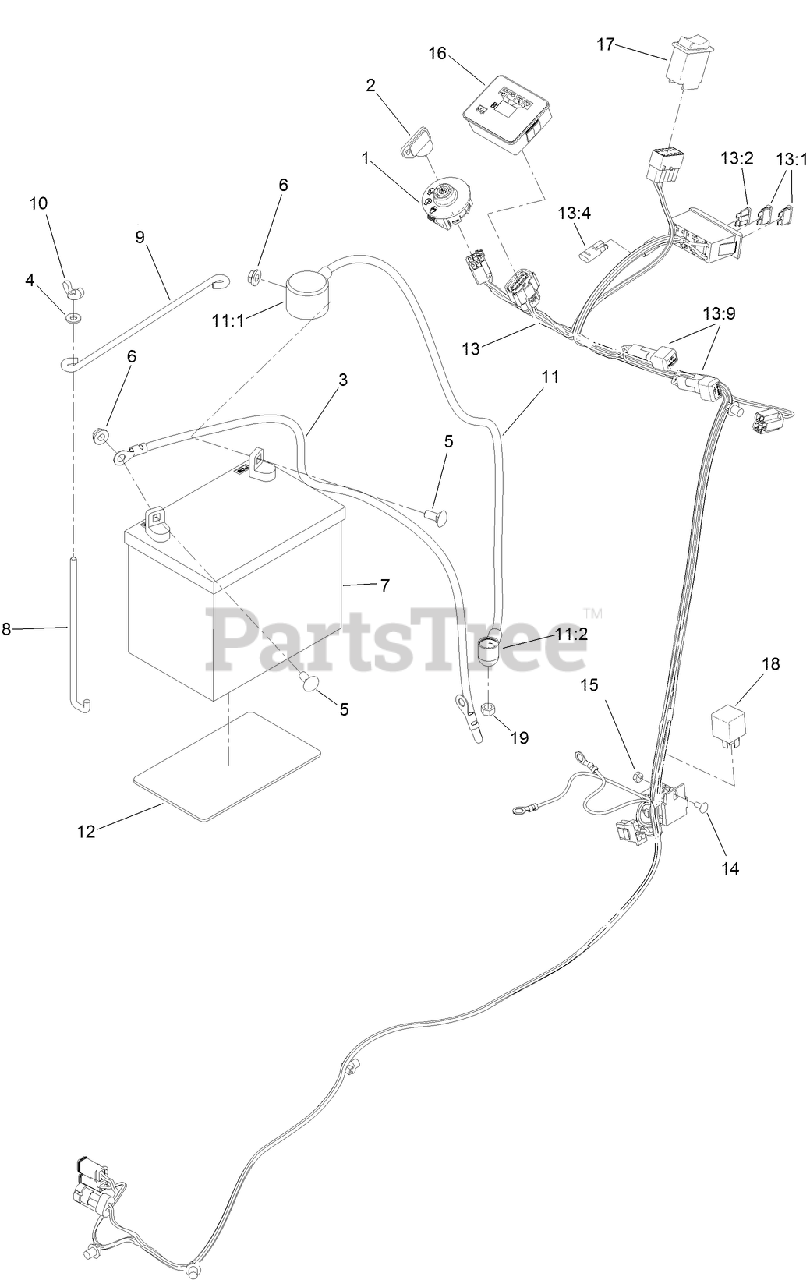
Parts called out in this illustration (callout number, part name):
1	SWITCH-IGNITION
2	KEY-IGNITION
3	CABLE-BATTERY, NEGATIVE
4	WASHER-FLAT
5	BOLT-CARR
6	NUT-HF
7	BATTERY (300 CCA, WET)
8	POST-BATTERY
9	ROD-HOLD DOWN, BATTERY
10	NUT-WING
11	POSITIVE BATTERY CABLE ASM
11:1	INSULATOR-BATTERY
11:2	INSULATOR-SOLENOID
12	PAD-SKID, ANTI
13	HARNESS-WIRE
13:1	FUSE-BLADE, 15 AMP
13:2	FUSE-BLADE, 7.5 AMP
13:4	CAP-PLUG
14	BOLT-CARR
15	NUT-LOCK, NI
16	MODULE, HOUR METER
17	SWITCH-ROCKER, 2 POLE
19	NUT-HEX
